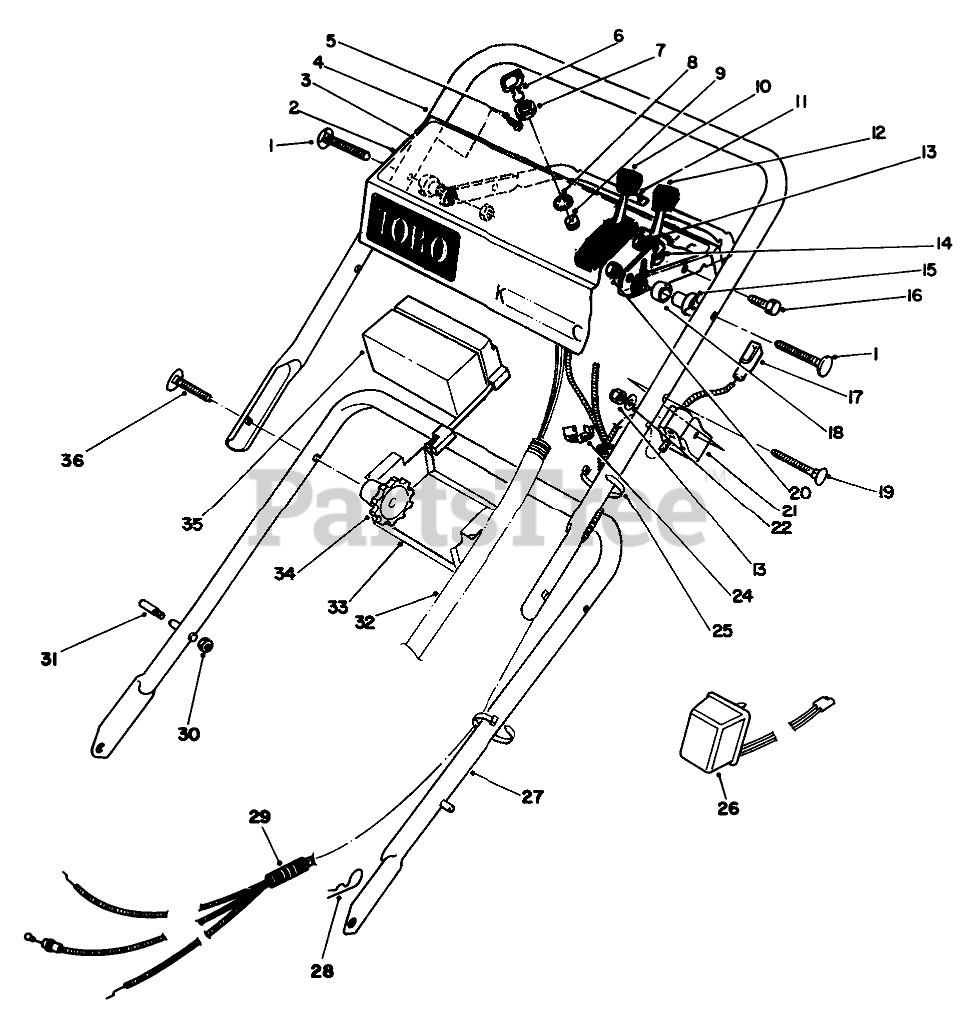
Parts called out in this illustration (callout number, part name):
1	5/16-18 X 2 HNDLE SCREW
2	Panel-Control (Incl. Ref. #3)
3	INSTRUCTION DECAL
4	Handle-Upper
5	SCREW-HWHTF
6	KEY-IGNITION
7	NUT-HH
8	WASHER-TOOTH, INTERNAL
9	Switch-Starter (Incl. Ref. #7 & 8)
10	Control-Traction (Bend Type #3) Sheath Lg. 46")(Wire Lg. 2")
11	Bar-Control
12	THROTTLE CONTROL
13	NUT-LOCK, NI
14	LEVER-CONTROL
15	SPACER-SUPPORT
16	SCREW-HH
17	BRAKE CABLE-SUZUKI
18	SPACER-NYLON
19	HANDLE SCREW
20	NUT-LOCK, NI
21	SUPPORT-CABLE
22	WASHER-FLAT
24	FITTING-RING
25	TIE-CABLE
26	Charger
27	LOWER HANDLE ASM
28	PIN-COTTER, HAIR
29	CONT. CABLE COVER
30	NUT-LOCK, NI
31	HANDLE PIN
32	WIRE HARNESS
33	BATTERY RETAINER
35	Battery
36	SCREW
